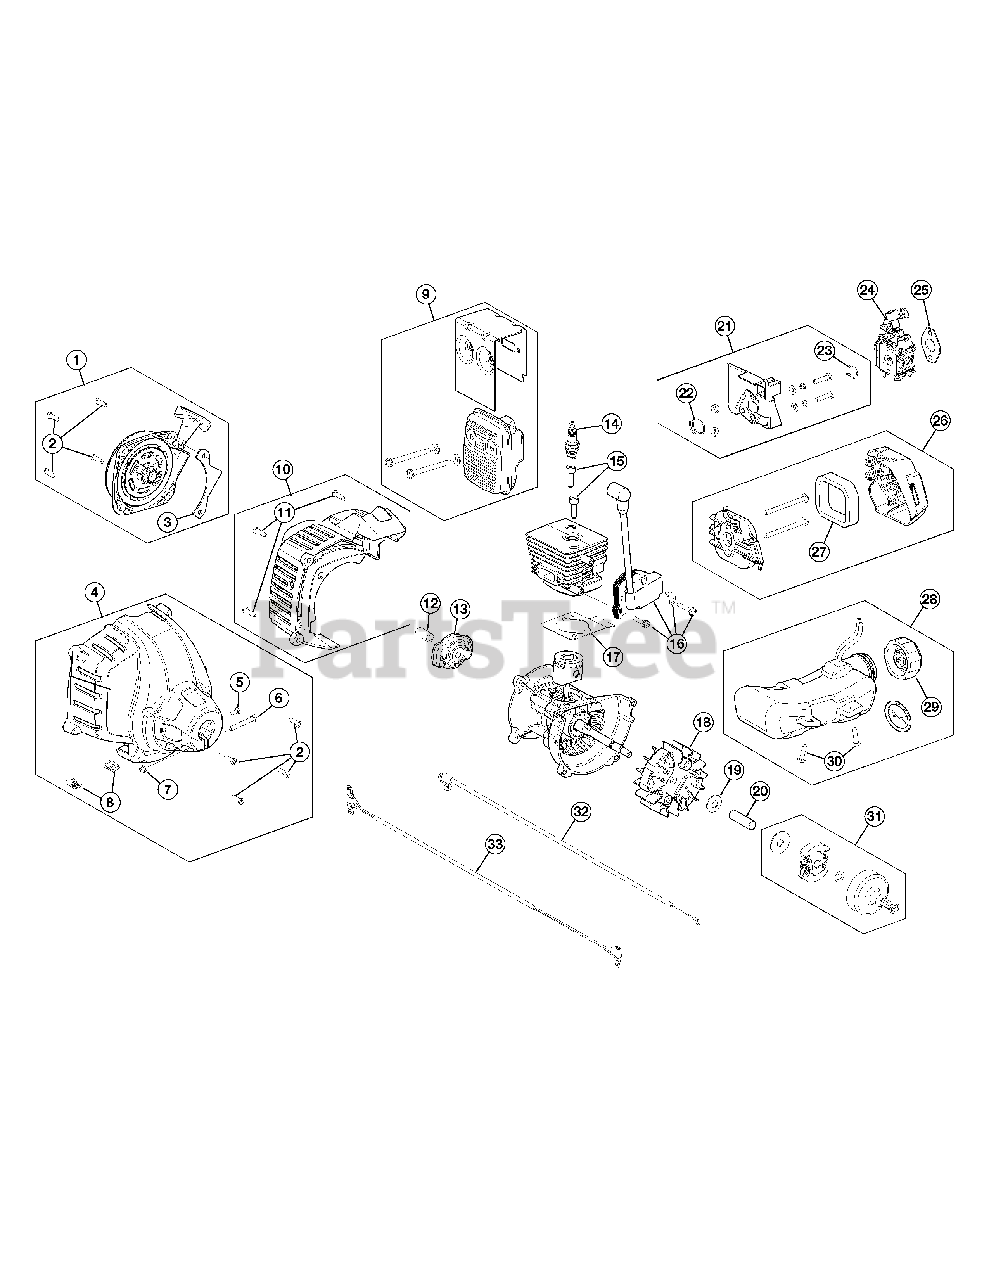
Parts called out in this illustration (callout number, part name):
1	Starter Assembly (Incl. 2 & 3)
2	Starter Screw
3	Starter Assembly Guard (Incl. 2)
4	Clutch Cover Assembly (Incl. 2, 5 - 8)
5	Anti-Rotation Screw
6	Clamp Screw
7	Clamp Nut
8	U-Shaped Nut
9	Muffler Assembly
10	Rear Engine Cover (Incl. 11)
11	Cover Screw
13	Pawl Assembly
14	Spark Plug
15	Cylinder Bolt
16	Module Assembly
17	Cylinder Gasket
18	Flywheel Assembly
21	Insulator Assembly (Incl. 22 & 23)
22	Insulator O-Ring
23	Carburetor O-Ring
24	Carburetor
25	Carburetor Gasket
26	Aircleaner Assembly (Incl. 27)
27	Aircleaner Filter
28	Fuel Tank Assembly (Incl. 29 & 30)
29	Fuel Tank Cap
30	Fuel Tank Screw
31	Clutch Assembly
32	Throttle Cable
33	Lead Wires
